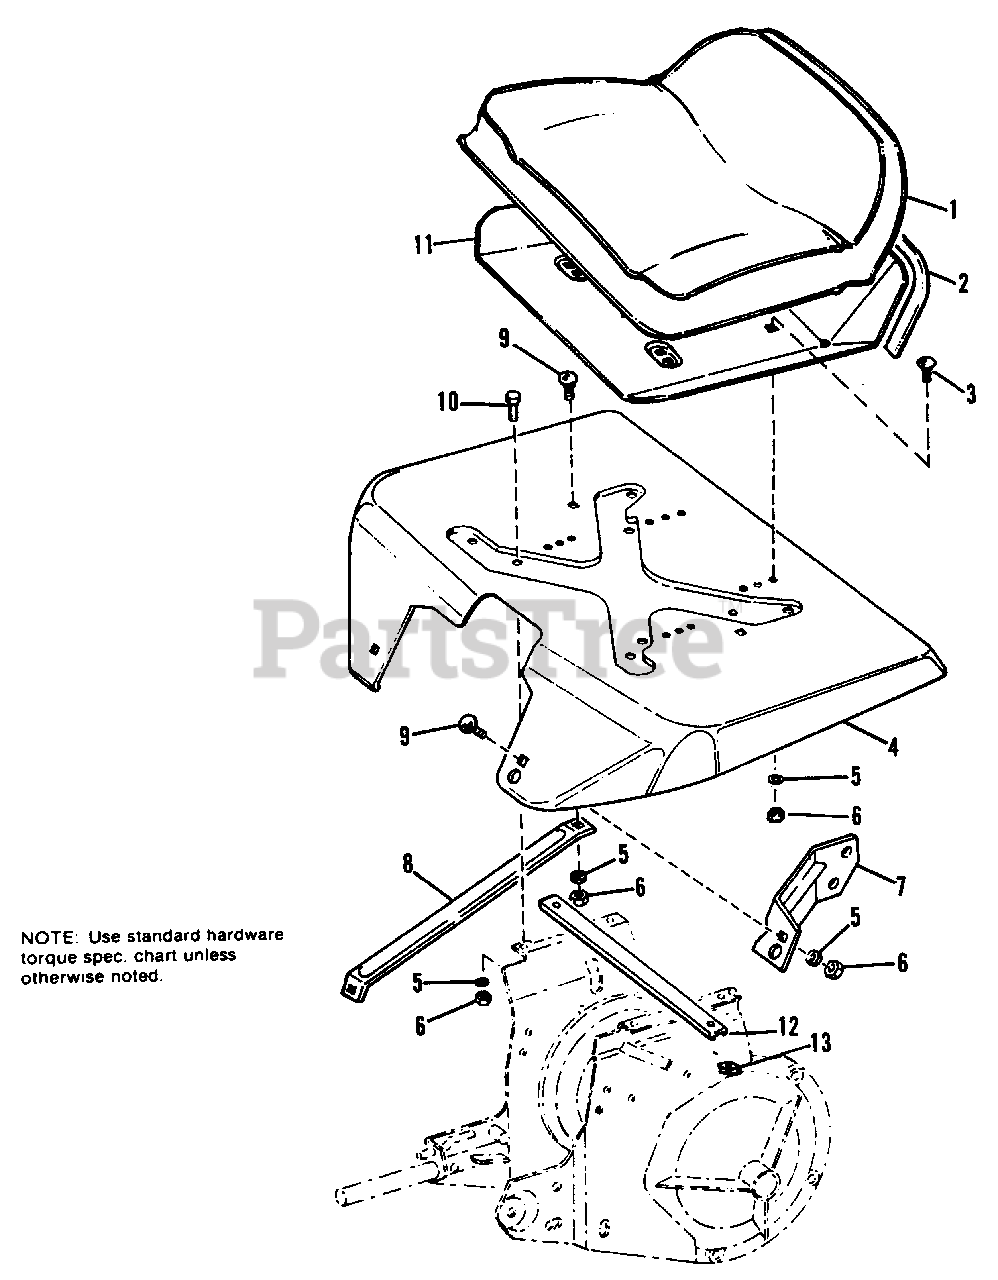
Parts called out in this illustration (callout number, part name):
1	PAD, Seat
1	SEAT ASSY. (990489)
2	TAPE, Seat Pan
3	BOLT, Carriage, 5/16-18 x 3/4
4	SUPPORT, Seat
5	LOCKWASHER, 5/16
6	NUT, Hex, Full, 5/16-18
7	BRACKET (990780, 990904 Only)
8	BRACE (Qty. 2 on 990577)
9	BOLT, Carriage, 5/16-18 x 1/2
10	CAPSCREW, Hex Hd., 5/16-18 x 3/4 (990489 & 990904 Only)
11	PANEL, Seat
12	SPACER (1690019, 1690020 Only)
13	NUT, Square, 5/16-18 (1690019, 1690020 Only)
